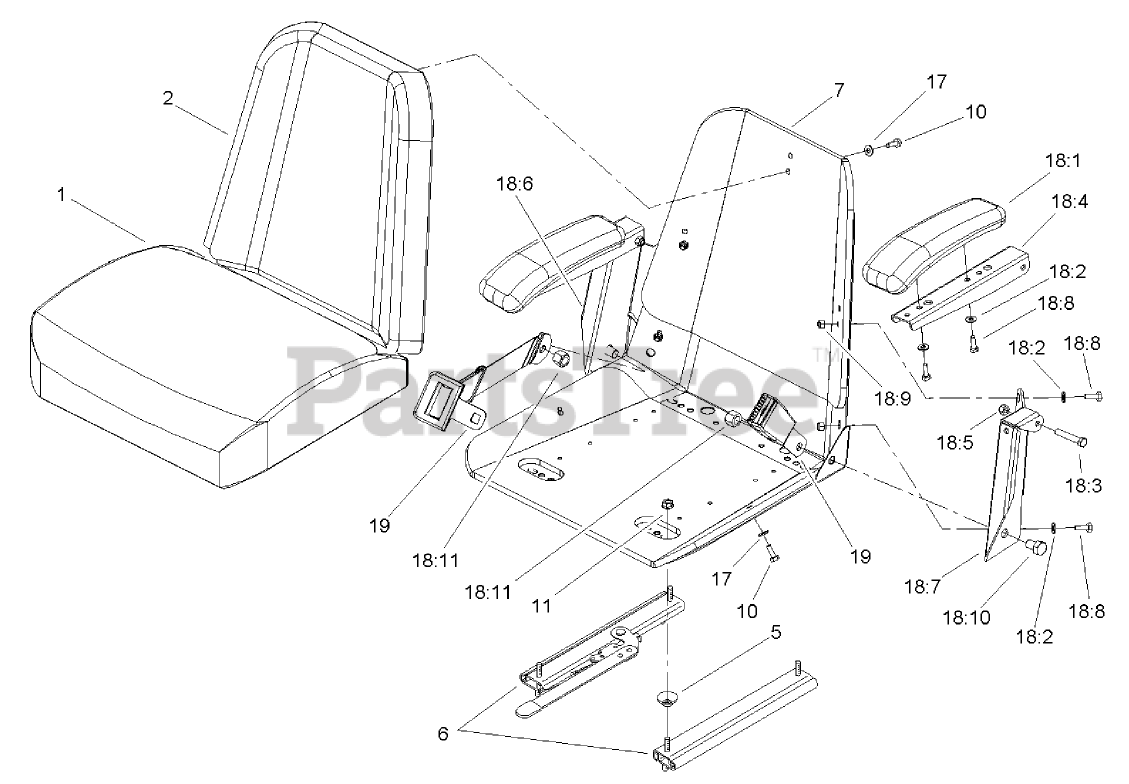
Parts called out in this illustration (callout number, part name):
1	CUSHION-SEAT, BOTTOM
2	CUSHION-SEAT, BACK
5	SPACER-TRACK
6	TRACK-SEAT
7	FRAME-SEAT
10	SCREW-HH
11	NUT-HF
17	WASHER-FLAT
18	ARMREST KIT
18:1	CUSHION-ARMREST
18:2	WASHER-FLAT
18:3	SCREW-HH
18:4	CHANNEL-ARMREST
18:5	NUT-HEX, SIDE DEFORM
18:6	Bracket-Armrest, RH
18:7	Bracket-Armrest, LH
18:8	SCREW-HH
18:9	NUT-LOCK, NI
18:10	SCREW-HH
18:11	NUT-LOCK, NI
19	Belt-Seat
